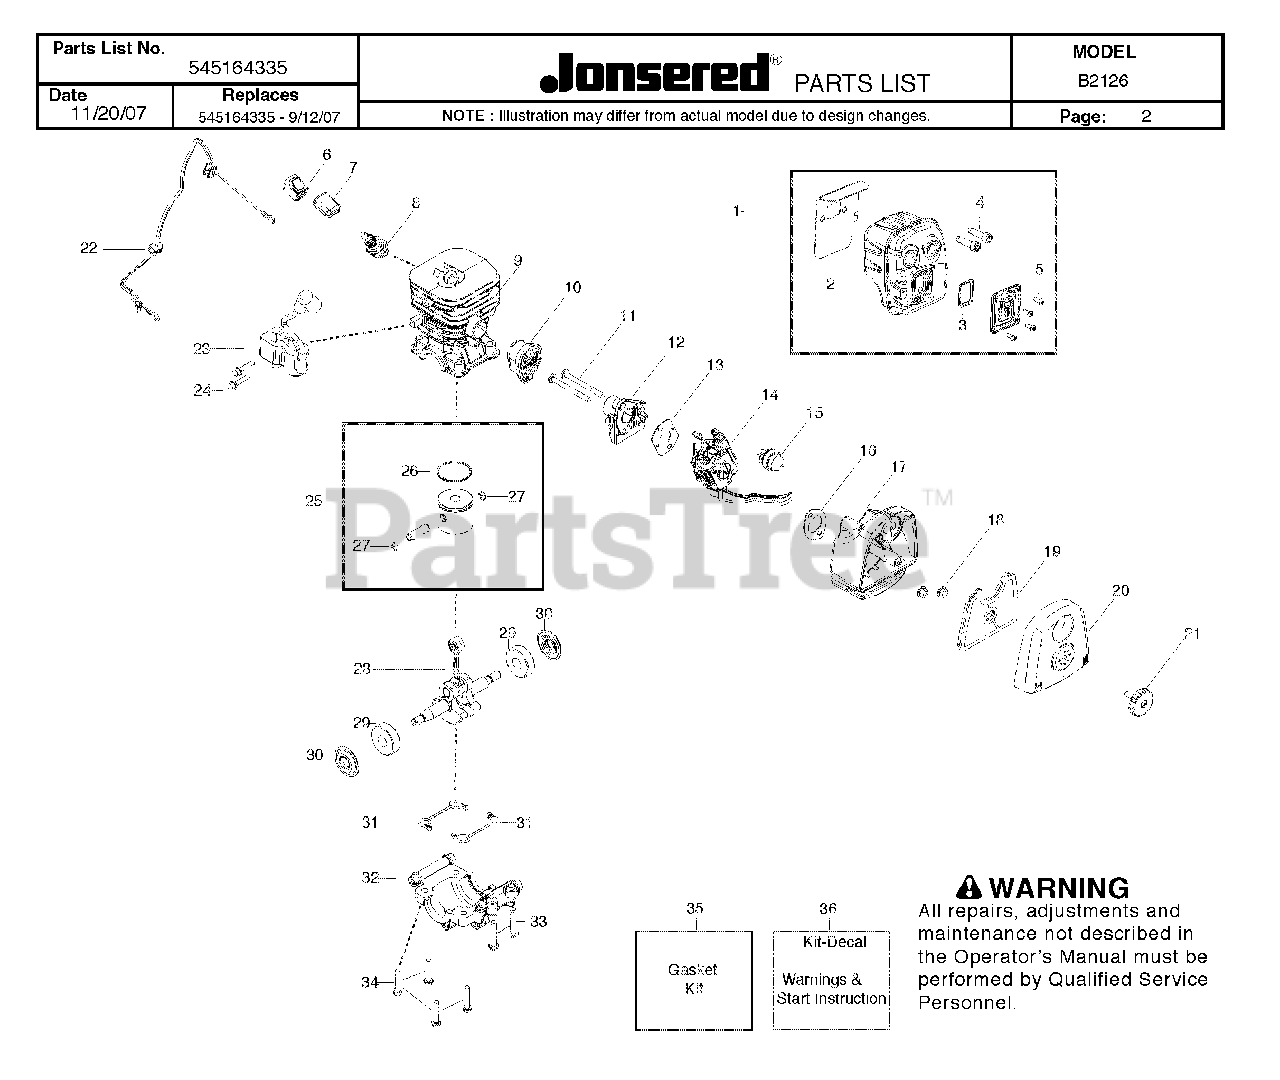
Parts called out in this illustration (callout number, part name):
1	ASSY, MUFFLER
3	KIT, SPARK SCREEN
4	BOLT MUFFLER
5	SCREW-6-19X5/16PLAST PA
6	KIT SWITCH
7	PROTECTOR, SWITCH
8	PLUG-SPARK (RCJ-6Y)
9	CYLINDER -CHROME
10	BOOT, CARB
12	PLATE, CARB
14	KIT, CARB
15	AIR PURGE
17	BASE - AIR BOX
19	FILTER, AIR
20	COVER - AIR BOX
21	ASSY - AIR BOX KNOB
22	ASSY, LEADWIRE
23	IGNITION MODULE
24	SCREW M4 X .70 TT 16MM
25	KIT - PISTON
26	RING PISTON
27	WRIST PIN RET.
28	KIT, CRANKSHAFT
29	BEARING RADIAL BALL (6201)
30	CRANKSHAFT SEAL
32	CAP - BEARING
34	B0LT, C/SHAFT 36/41
